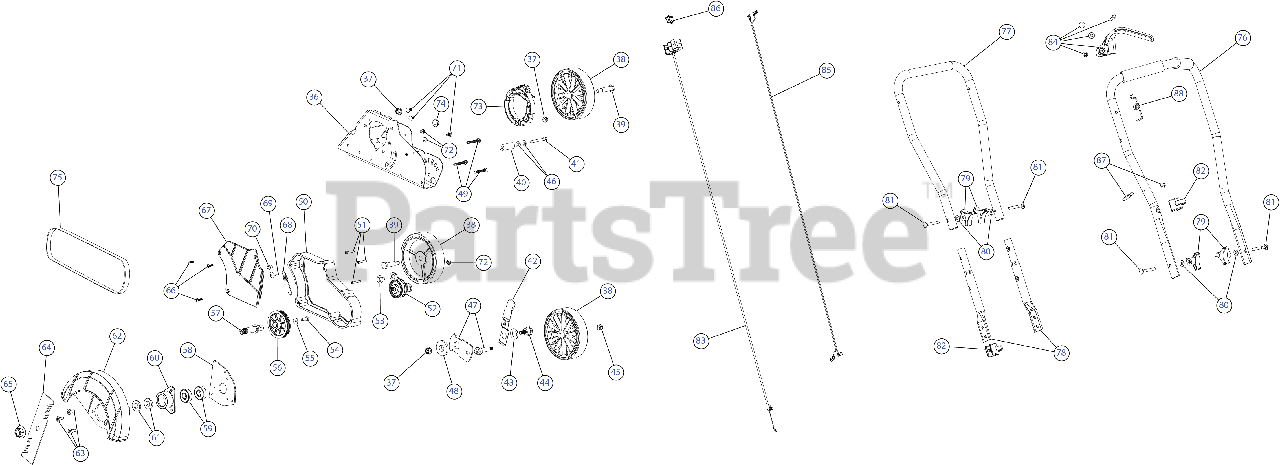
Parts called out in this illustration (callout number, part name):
38	WHEEL 5-1.5 GRAY
39	SHOULDER SCREW
40	SPACER
41	SCREW 1/4-20 x 2.375
42	Height Adjustment Lever Assembly
43	BELL WASHER
44	SHOULDER SCREW .75 X.50 X3/8-16
45	HEX NUT INS L-3/8-16
46	SPACER
47	PIVOT ARM
48	BEARING
49	SCREW 1/4-20 x 1.750
50	SPACER
51	SCREW 8-16X1.25
52	IDLER PULLEY ASSEMBLY
53	SHOULDER SCREW .560X.165: 5/16-18
54	SCREW 1/4-20X.75 GR5
55	SPRING WASHER BELL
57	BLADE SPINDLE
58	SPINDLE MOUNT PLATE
59	BALL BEARING
60	BEARING CUP
61	FLAT WASHER .635X1.24X.181
62	EDGER BLADE GUARD (W/LABEL)
63	SHOULDER SCREW .375X.280:1/4-14
64	EDGER BLADE
65	HEX NUT
66	SCREW 8-16 x 3/4
67	BELT COVER
68	SPRING
69	BOLT 1/4-20
70	SCREW 1/4-20 X.500
71	BOLT 1/4-20X.50
72	FLANGE LOCK NUT
73	SPACER
74	NUT 5/16X18
76	HANDLE UP
77	HANDLE MID
78	HANDLE EXT
79	KNOB, 3-PRONG ¼ "-
80	WASH, FLAT SPECIAL
81	BOLT, CARRIAGE CRV
82	CABLE GUIDE
83	THROTTLE CABLE
84	THROTTLE LVR W/HDW
85	WIRE LEAD
86	SW, MOMENTARY ON/O
87	ROPE GUIDE
88	SPRING
